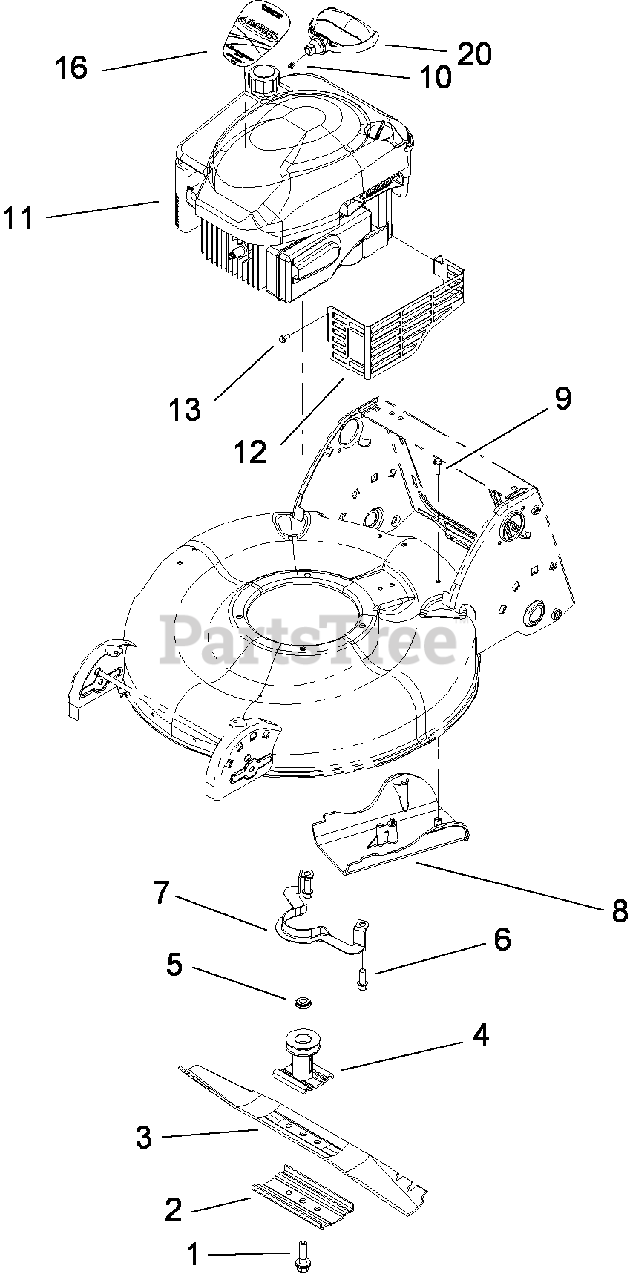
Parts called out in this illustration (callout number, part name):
1	BOLT-BLADE
2	SUPPORT-BLADE
3	BLADE-21 INCH
4	BLADE DRIVER ASM
5	Spacer-Driver
6	SCREW-HWH
8	COVER-BELT
9	SCREW-HWH
10	STOP-ROPE
12	SHIELD-MUFFLER
13	SCREW-TAPTITE
16	DECAL-ENGINE
20	HANDLE-RECOIL
